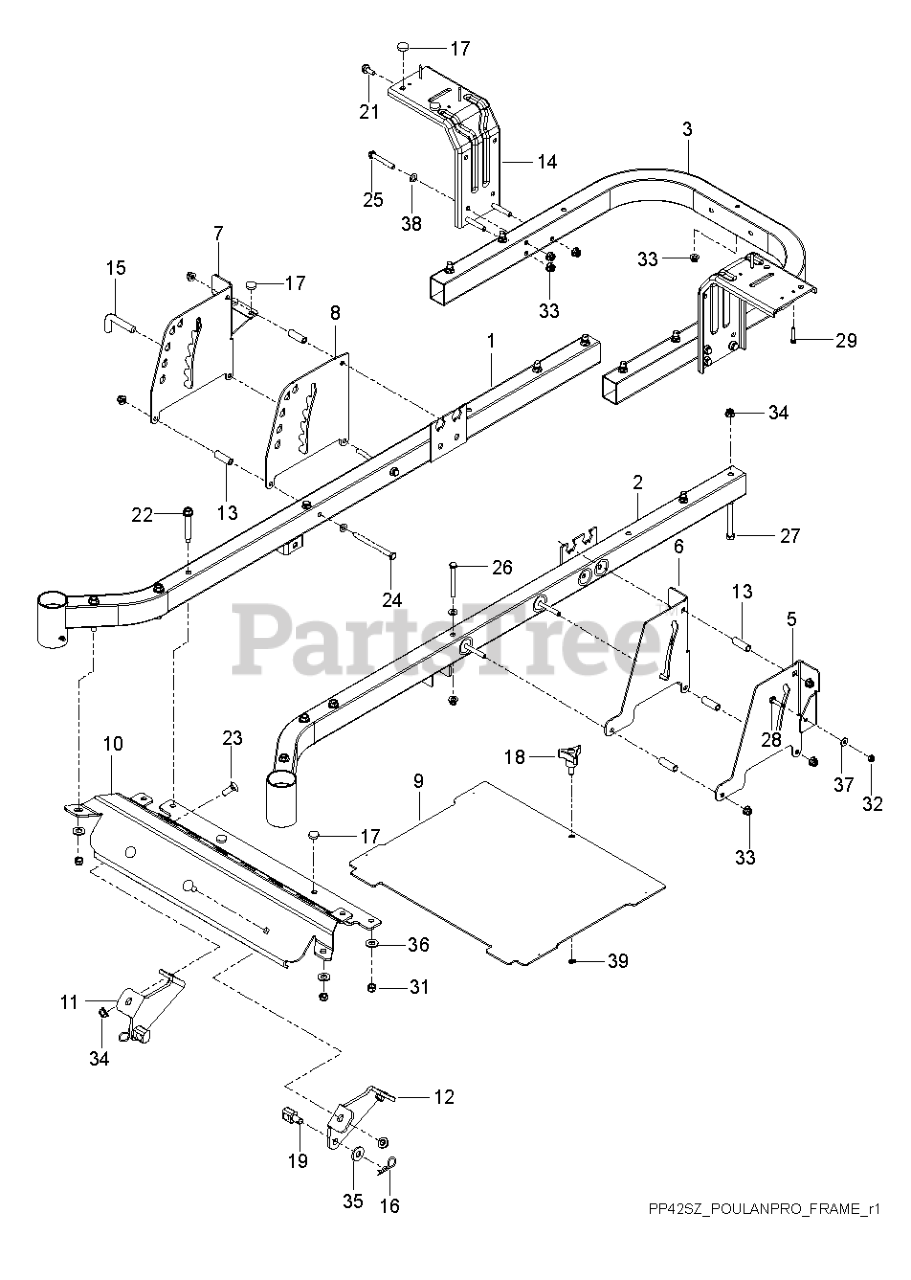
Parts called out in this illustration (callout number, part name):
1	FRAME TUBE RZ MAIN WELDMENT RI
2	FRAME TUBE RZ MAIN WELDMENT LE
3	FRAME.PNT.REAR.TUBE.BLACK
5	PLATE OUTER BRAKE BLACK MS-431
6	PLATE, BRAKE LATCH, BLACK
7	PLATE.DECK HEIGHT.PNT.431.RZ
8	PLATE, DECK HEIGHT, BLACK
9	PLATE, FOOT W/DECALS, BLK
10	FOOT REST, MED BLK
11	MOUNT.STRUT.RH.431
12	MOUNT.STRUT.LH.431
13	SPACER.334.ID.5.OD.1.5.L
14	FENDER.SUPPORT.PNT.X431
15	PIN.DECK.HEIGHT.RZ
16	HAIRPIN #4
17	GROMMET, BUMPER
18	KNOB W/STUD
19	SWIVEL.TRUNION.LINK.DECK.FRONT
21	HHFS 5/16-18 X 3/4
22	HHFS 3/8-16 X 2-3/4 GR5 ZD
23	RHSNB 3/8C X 1
24	HCS 5/16C X 4
25	Bolt Fin Hex 5/16-18 x 2-1/4 (AYP part number)
26	Bolt Fin Hex 5/16 - 18 UNC x 2.75 (AYP part number)
27	BOLT.HEX.FIN.3/8-16 X 3.GR5
28	BOLT
29	SCR #10-12X1-1/2HEX WASH HD ZD
31	NUT HEX 3/8-16 NYLON, THIN
32	NUT 1/4-20 NYLOC
33	5/16-18 NYLOC FLANGE NUT
34	NUT 3/8-16 HEX FLG NYLOC ZD
35	WASHER
36	WASHER 3/8 FLAT
37	Washer 9/32 x 5/8 x 16 Gauge (AYP part number)
38	Washer, Nut Lock Hex w/Ins. 5/6-18 (AYP part number)
39	WASHER 5/16"
